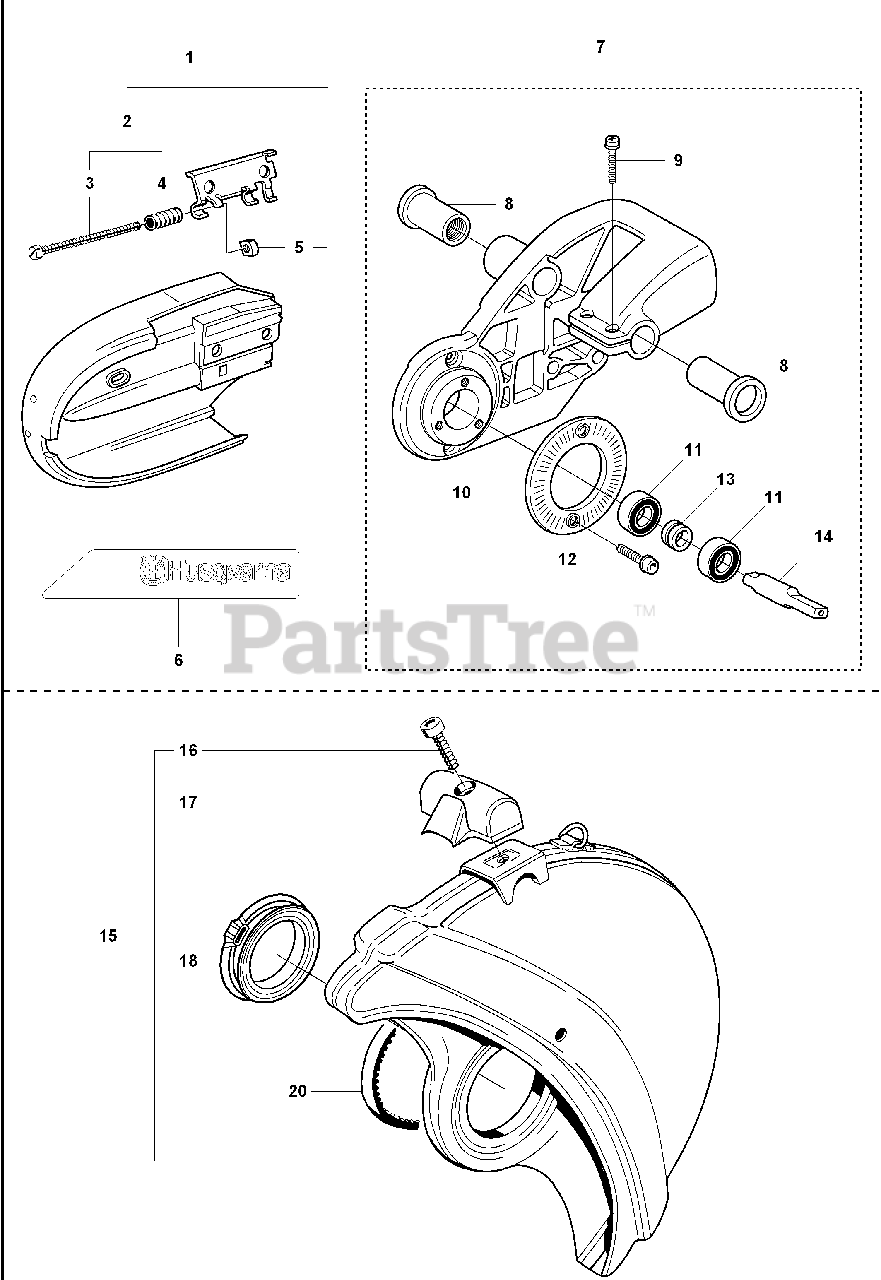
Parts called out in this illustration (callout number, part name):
1	BELT GUARD
2	BELT TENSIONER ASSY
4	COMPRESSION SPRING
7	BEARING HOUSING
10	SCREEN PATTERN FLANG
11	BALL BEARING
13	SPACING SLEEVE
15	WHEEL GUARD ASSY
16	SCREW
19	BELT
